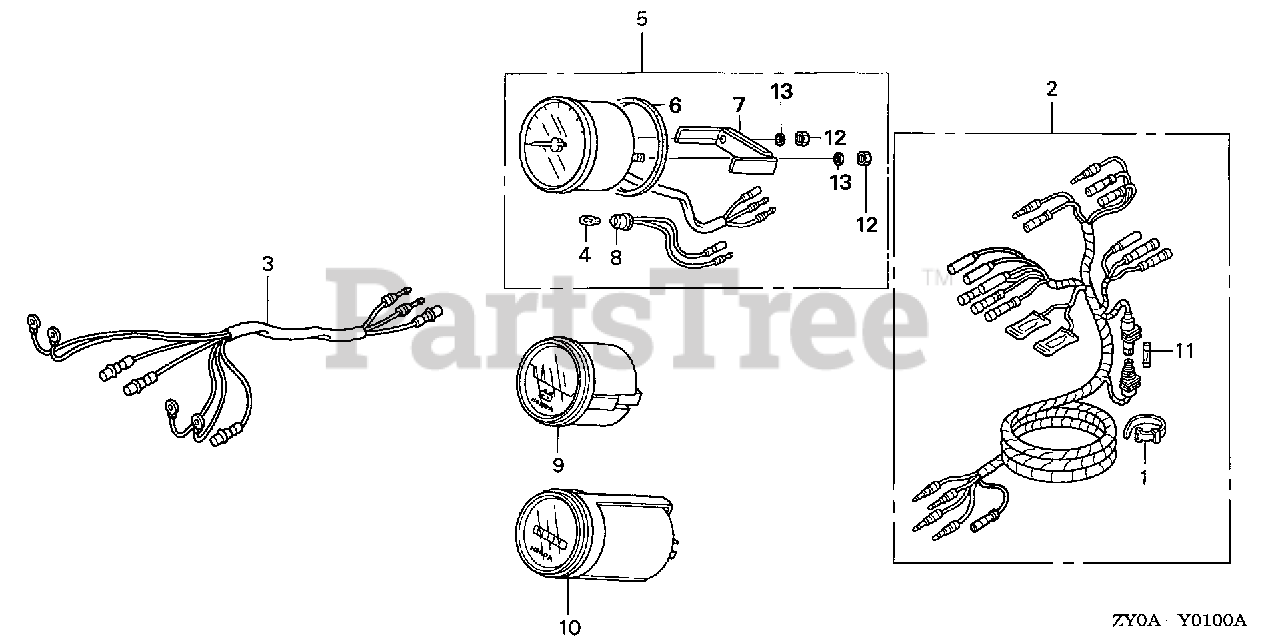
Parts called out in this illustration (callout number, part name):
1	BAND B1, WIRE
2	HARNESS ASSY., METER (A)
3	HARNESS ASSY., METER (B)
4	BULB, WEDGE BASE (T10) (12V 1.7W) (STANLEY)
5	TACHOMETER ASSY.
6	GASKET
7	BRACKET
8	SOCKET
9	METER ASSY., VOLT
10	METER ASSY., HOUR L.C.D.
11	FUSE A (10A)
12	NUT, HEX. (5MM)
13	WASHER, SPRING (5MM)
